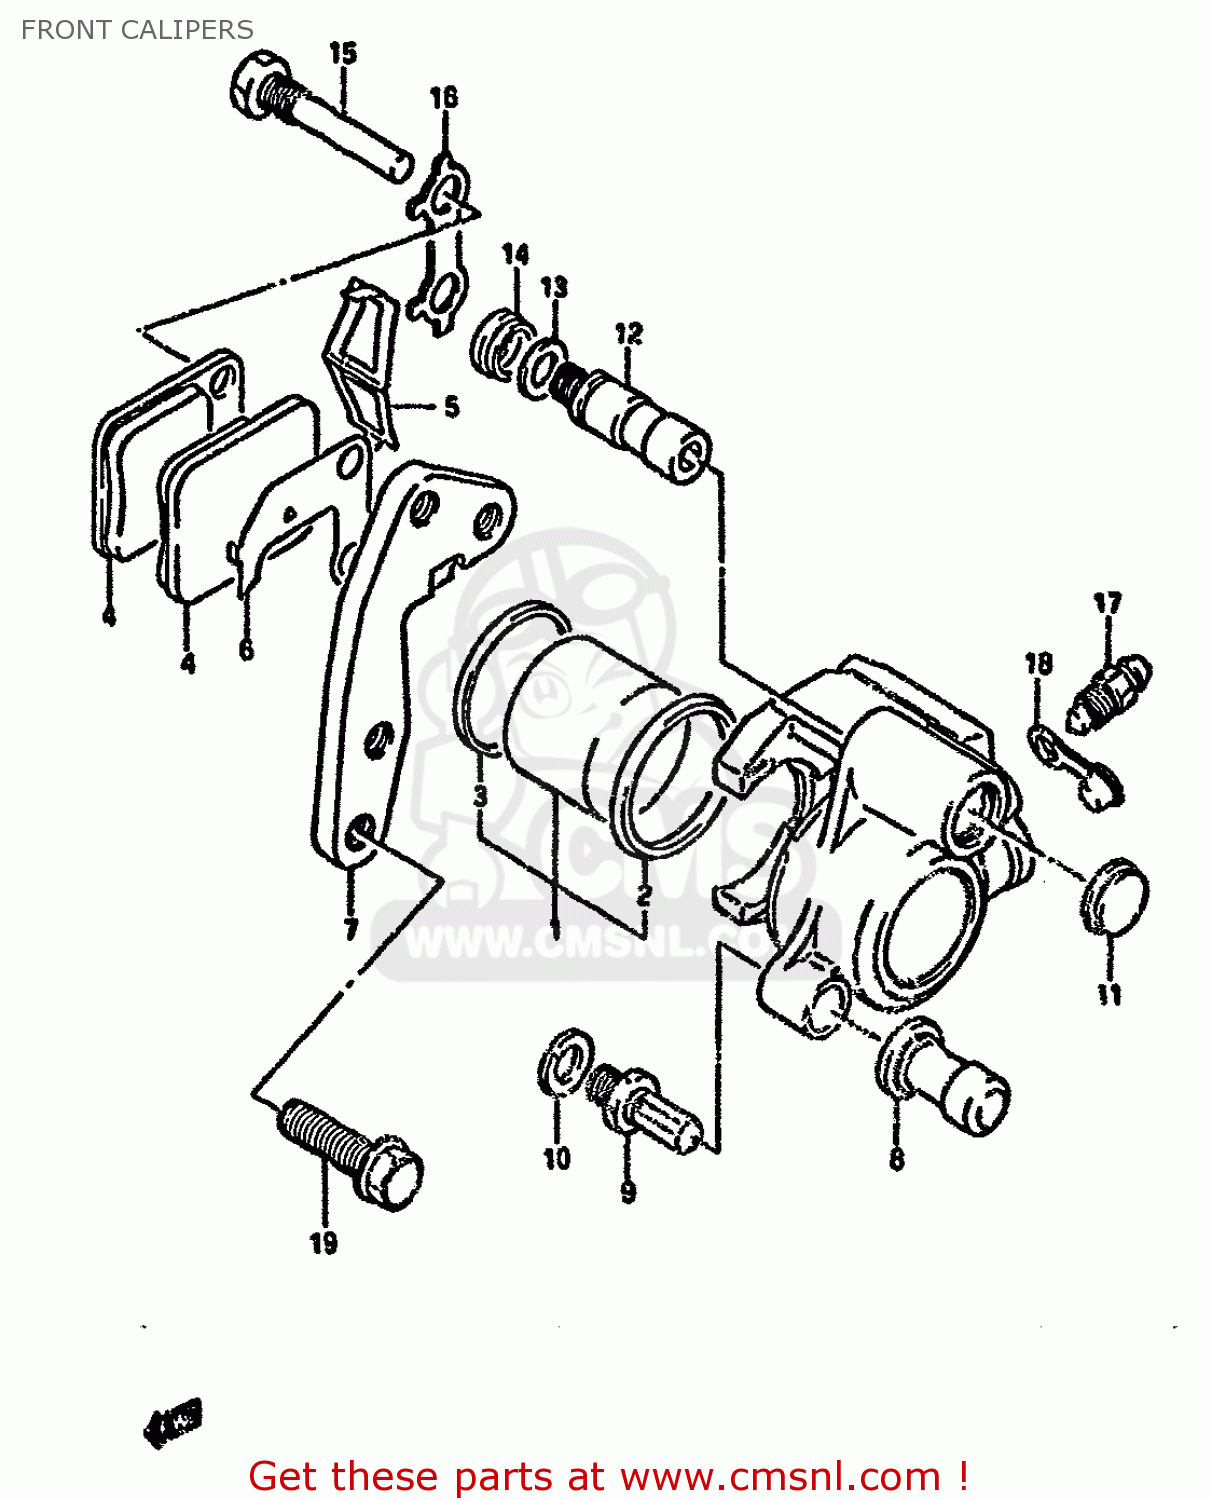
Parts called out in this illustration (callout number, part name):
1	PISTON SET,CALIPERS
2	SEAL,PISTON
3	BOOT,PISTON
4	PAD
5	SPRING,PAD
6	SHIM
7	BRACKET
8	BOOT
9	BOLT,PIN
10	WASHER,WAVE
11	DUST SEAL
12	PIN,SLIDE
13	SPRING,FRICTION
14	BOOT,PIN
15	PIN,HANGER
16	WASHER
17	BLEEDER
18	CAP,BLEEDER
19	BOLT 8X30
